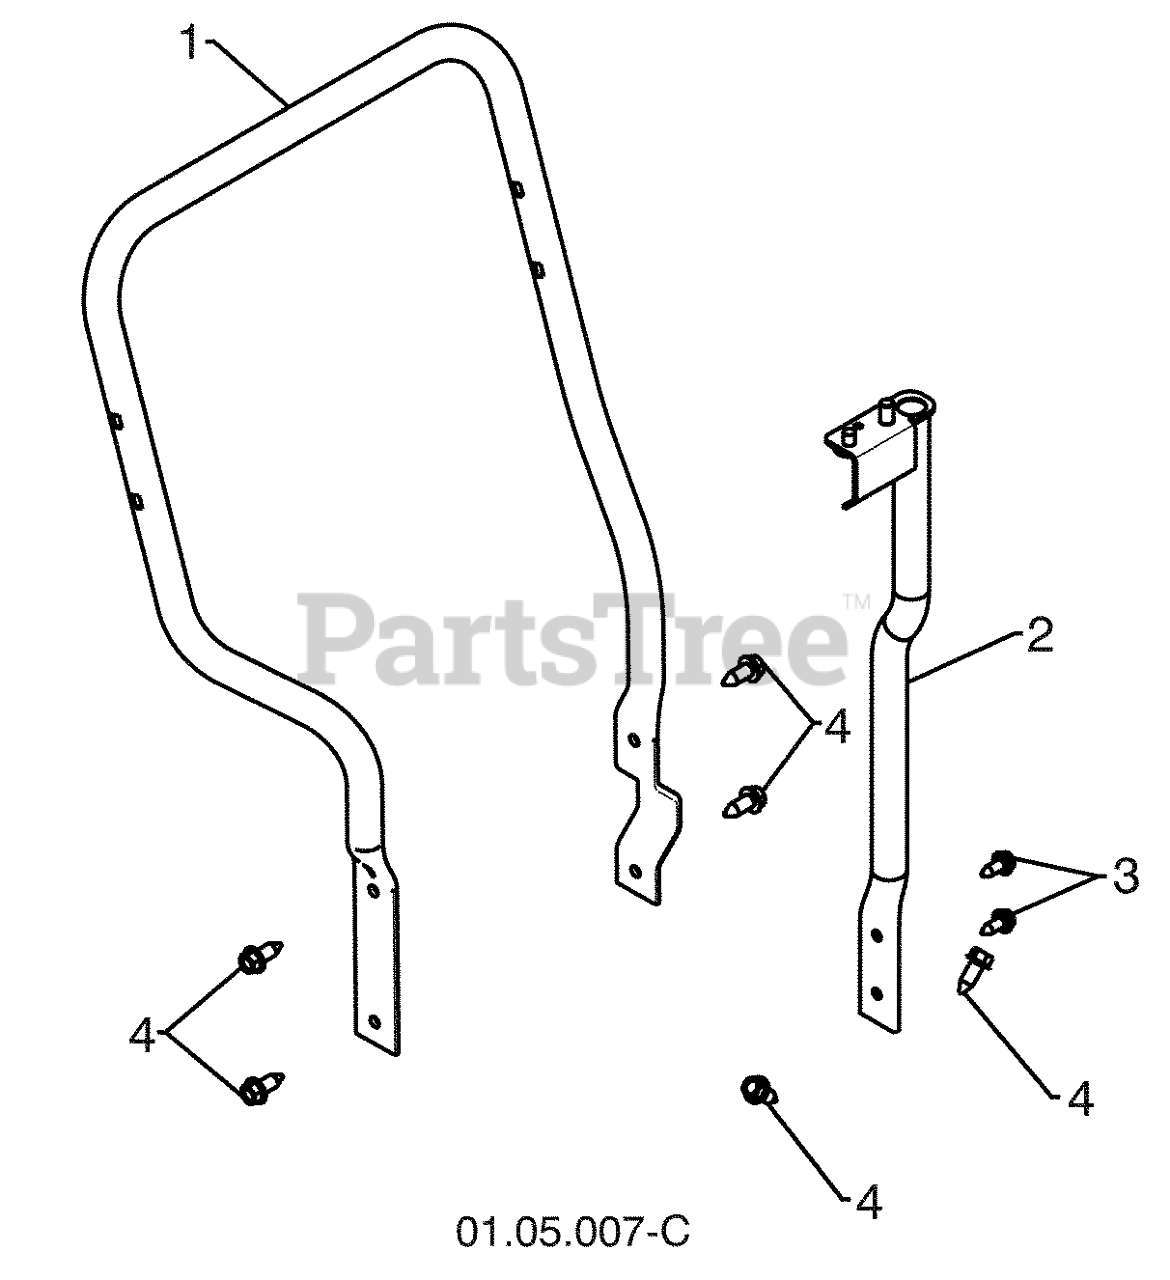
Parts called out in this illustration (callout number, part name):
1	TUBE.LOWER.HANDLE.SNOW.GRAY
2	SUPPORT.WELDMENT.ROTATOR.
3	BOLT.HEX.HD.WASHER.5/16-18X.75
4	SCREW 3/8-16X1
